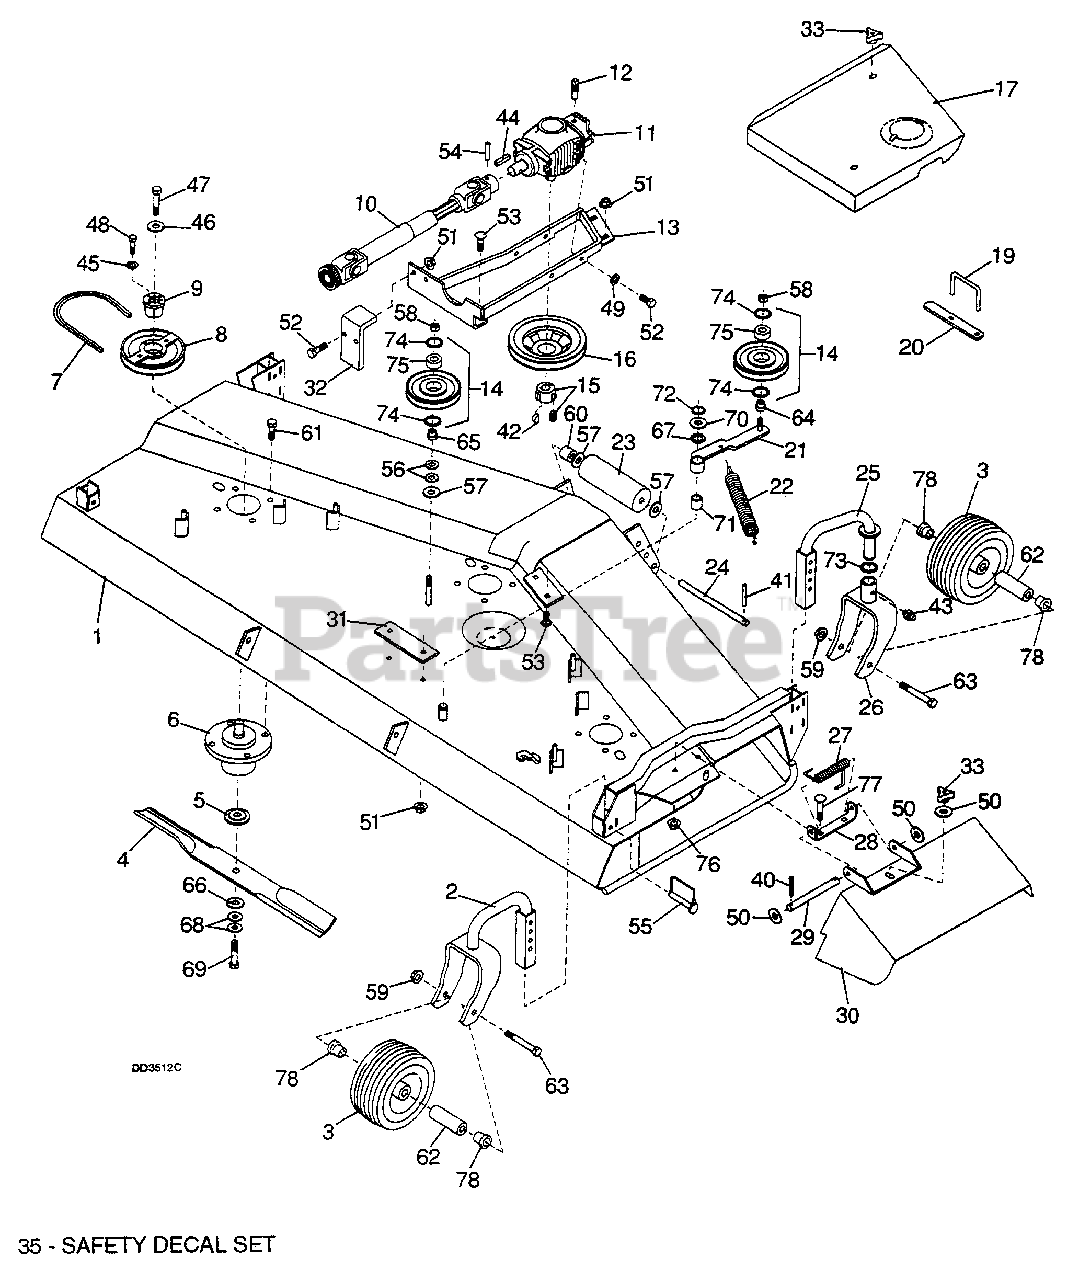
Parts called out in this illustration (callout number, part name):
1	Frame
2	3.5 x 9.5 Wheel Clevis & Handle
3	7.75 x 3.5 x .75 Wheel
4	CW 24.66 Blade Kit w/Hdwe
5	5/8 x 3 x 7.16 Shoulder washer
6	Spindle assembly
7	V-Belt WW133
8	Sheave, 5.40, 1, B, 1.625
9	H3/4 Bushing with key and hardware
10	Drive shaft assembly
11	Gearbox assembly
12	Gearbox vent plug
13	Gearbox mounting stand
14	Idler sheave with bearing
15	.81 Bore taper lock bushing w/hardware
16	1 BF 7.0 Offset sheave
17	Right belt shield
19	Spindle lock wrench
20	Spindle wrench handle
21	Idler arm assembly with bushing
22	.2 x 1.45 x 8.1 External spring
23	Roller, 2.38 Dia x 7
24	.5 x 9.75 Pin
25	Front gauge wheel arm
26	Caster clevis 9.5
28	Deck bracket
29	3/8 x 7-1/4 Pin
30	Discharge chute
31	Link, .18 x 1.5 x 5.38
32	Lug, Bent .38 x 2.5 x 3.75
33	3-Prong knob
35	Safety decal set
40	3/16 x 1 Cotter pin
41	3/16 x 1-1/8 Spring pin
42	Woodruff key 3/16 x 3/4
43	1/4-28 Taper threaded grease fitting
44	1/4 x 1/4 x 7/8 Key
45	1/4 Standard lockwasher
46	1/4 x 7/8 x 7GA Washer
47	1/4 NC x 3/4 Hex head cap screw GR5
48	1/4 NC x 1 HHCS GR5
49	3/8 Standard lockwasher
50	3/8 Standard flat washer
51	3/8 NC Flanged hex locknut
52	3/8 NC x 1 Hex head cap screw GR5
53	3/8 NC x 1 Carriage bolt GR5
54	Spirol pin 3/8 x 1-1/2
55	Lynch pin 3/8 x 2-1/4
56	.50 x .88 x 18GA Shim washer
57	1/2 Standard flat washer
58	1/2 NC Hex locknut
59	1/2 NC Flanged locknut
60	1/2 x 3/4 x 3/4 Sleeve
61	1/2 NF x 1 Hex head cap screw GR5
62	1/2 x 3/4 x 3-3/8 Sleeve
63	1/2 NC x 5 Hex head cap screw GR5
64	Shoulder sleeve, .5 x .9 x .76
65	Shoulder sleeve, .667 x .81 x 1.23
66	3/8 Standard flat washer
67	5/8 x 1 x 1/4 Felt seal
68	5/8 x 1-3/4 x 14GA Cup washer
69	5/8 NC x 2 Nylok Hex head cap screw GR5
70	3/4 x 1-1/2 x 18GA Shim washer
71	3/4 x 1 x 1 Oilite bushing
72	Retaining ring, External
73	Retaining ring, .078 x 1
74	Retaining ring, Internal
75	Bearing 6203
76	3/8 NC Spirol lock flange nut
77	3/8 NC x 1-1/4 Carriage bolt
78	3/4 x 1.415 Flanged bearing
